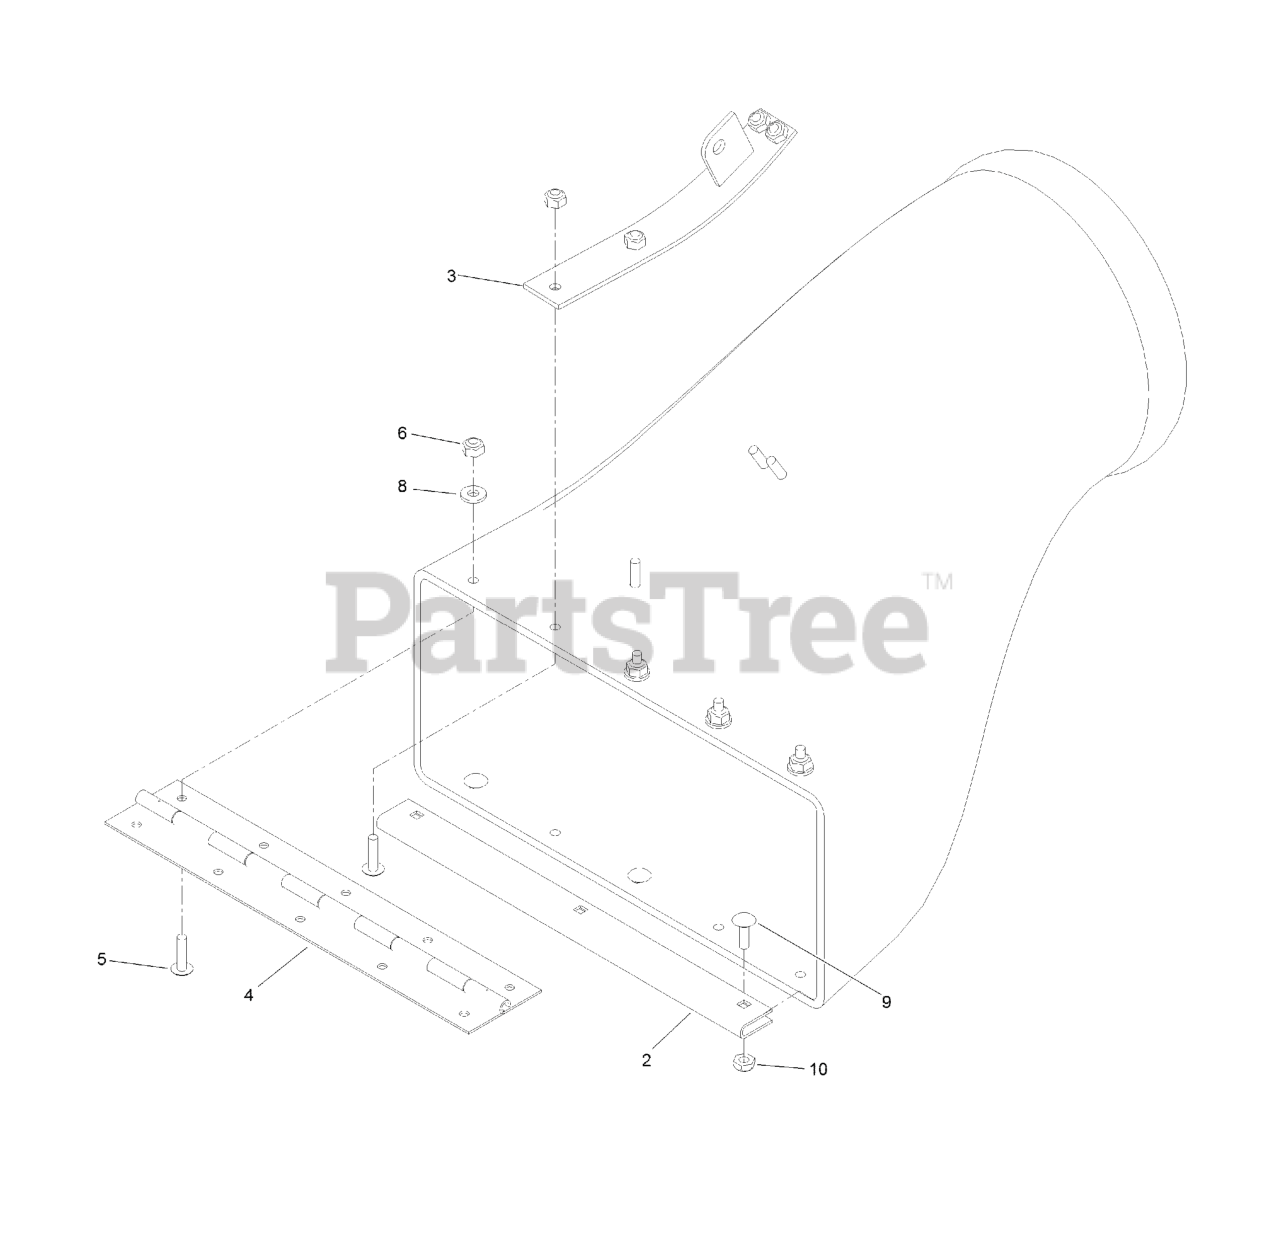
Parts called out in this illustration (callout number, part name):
2	GUARD-PLENUM
3	MOUNT-SPRING
4	HINGE-PIANO
5	SCREW-HEAD, TRUSS
6	NUT-LOCK, NI
8	WASHER-FLAT
9	BOLT-CARR
10	NUT-LOCK, NI
